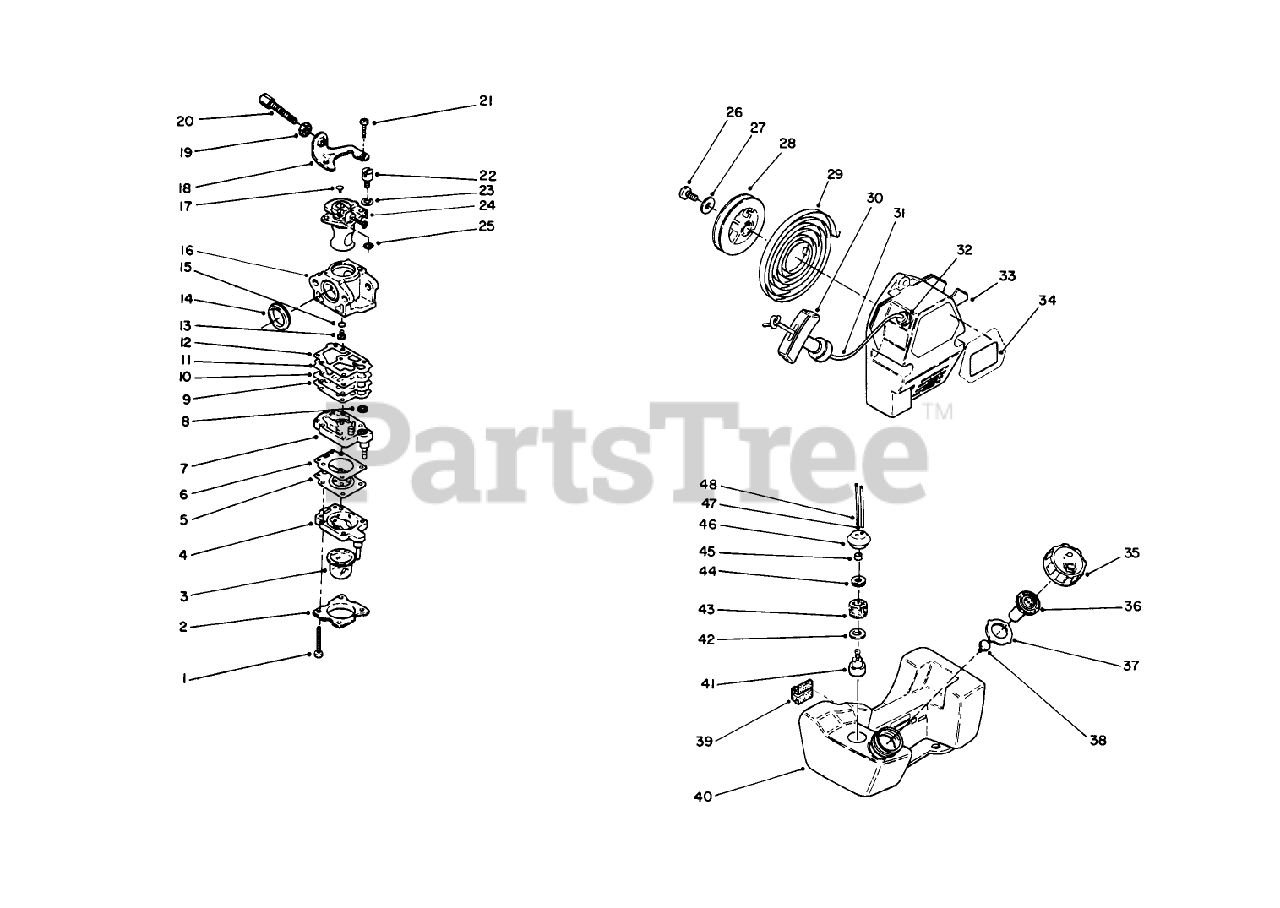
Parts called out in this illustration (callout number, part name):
3	PRIMER PUMP
5	DIAPHRAGM
6	DIAPHRAGM GASKET
7	PUMP BODY
8	SCREEN
9	PUMP GASKET
11	DIAPHRAGM
12	DIAPHRAM GASKET
14	RUBBER CARB GASKET
15	MAIN JET O-RING
16	Body-Carburetor (Ref.)
18	BRACKET
23	WASHER
24	THROTTLE VALVE
33	RECOIL CASE
35	FUEL TANK CAP
36	BREATHER VALVE
37	PACKING
45	COLLAR
46	FUEL TANK GROMMET
48	RETURN FUEL HOSE
